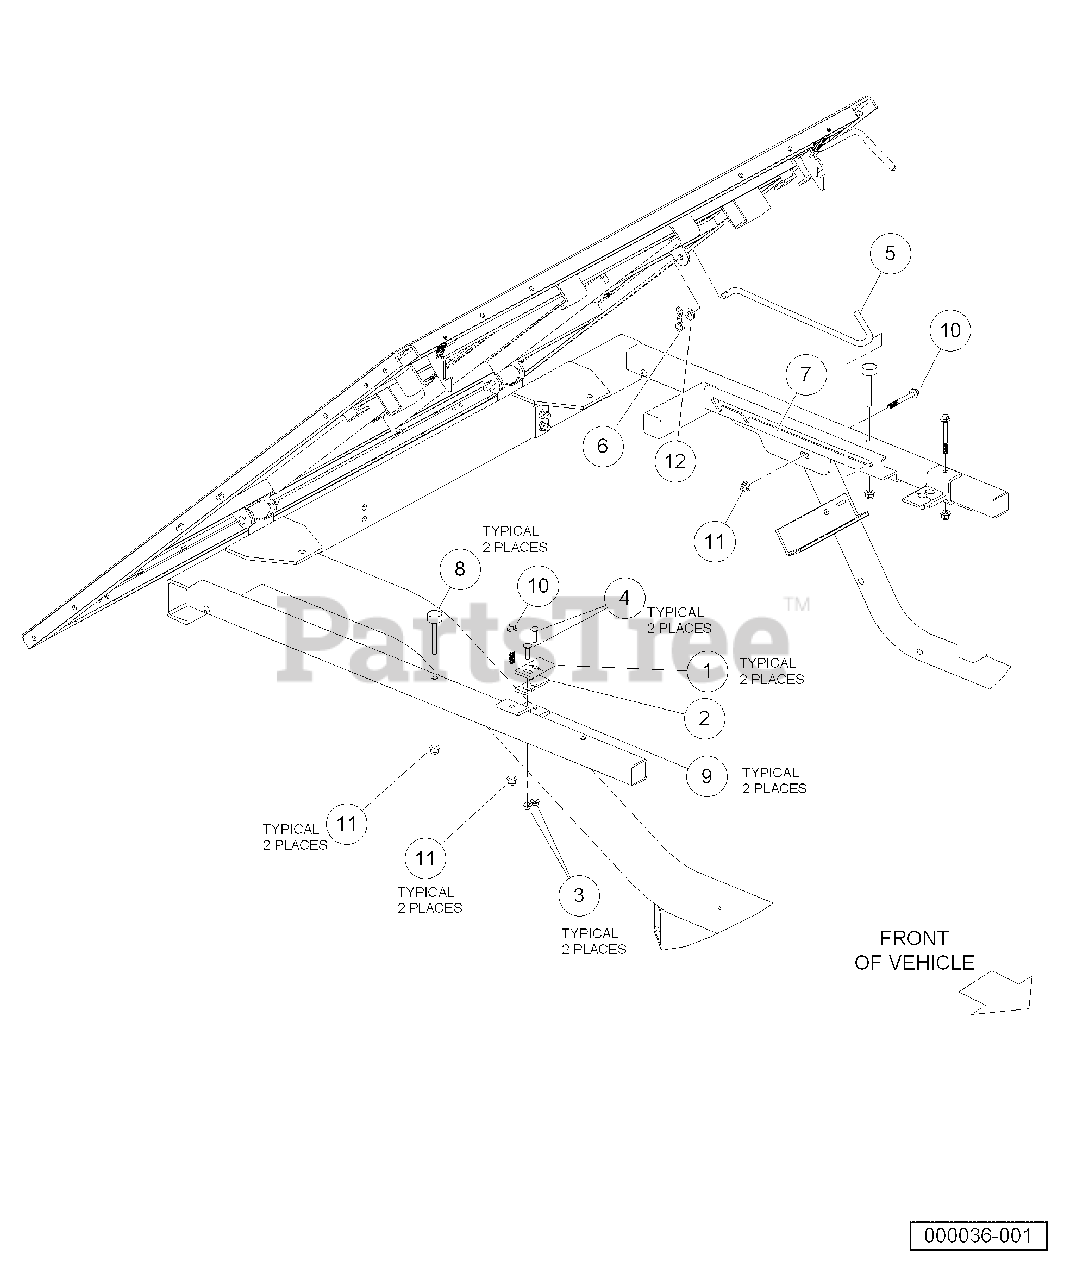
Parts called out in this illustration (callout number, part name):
1	Latch Plate, Tilt Bed
2	Latch Plate Shim
3	Locknut, 1/4-20 Hex Whiz
4	Bolt, Carriage, 1/4-20 X 1.0
6	Pin, Bow Tie Locking
7	Track, Prop Rod
8	Bumper, Bed, Mtg, Front
9	Bracket, Latch, Bed
10	Bolt Flanged Head, M8 X 1.25 X 65
11	Lock Nut, Flg M8 X 1.25 Nylon
12	Washer, 3/8 Type A Flat
